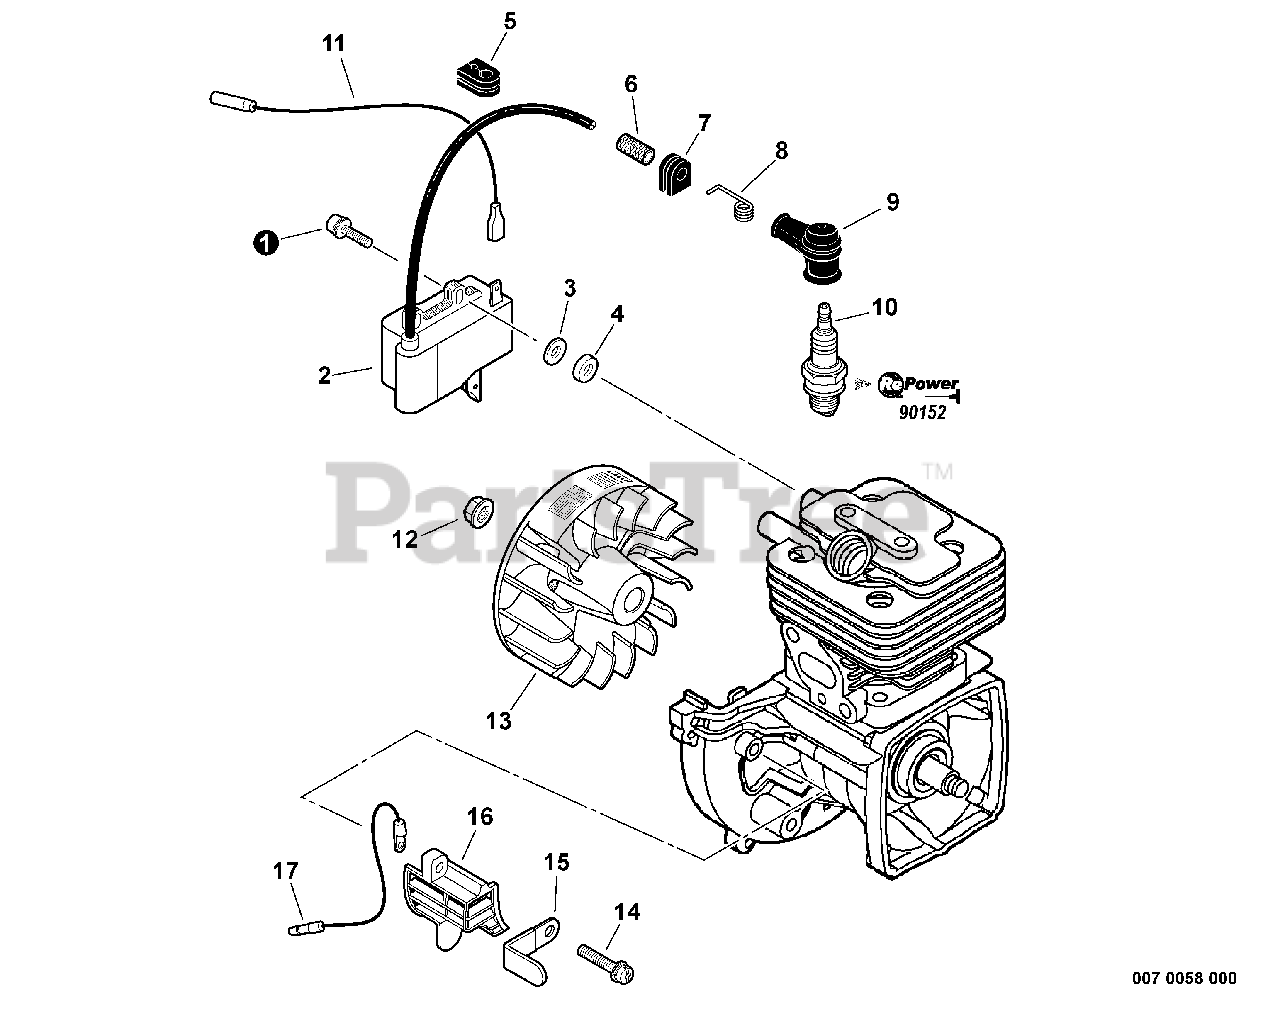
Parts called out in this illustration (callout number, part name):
1	SCREW - 4
2	COIL, IGNITION
3	WASHER - 4
4	INSULATOR
5	GROMMET
6	INSULATOR
8	TERMINAL, SPARK PLUG CAP
9	CAP, SPARK PLUG
10	SPARK PLUG -- BPM-8Y
10	SPARK PLUG -- BPMR-8Y
11	LEAD - IGNITION
12	NUT - 8 -- FLANGE
13	FLYWHEEL
14	SCREW - 5X16
16	GUARD, DEBRIS
17	LEAD - GROUND
18	RePower TUNE-UP KIT
